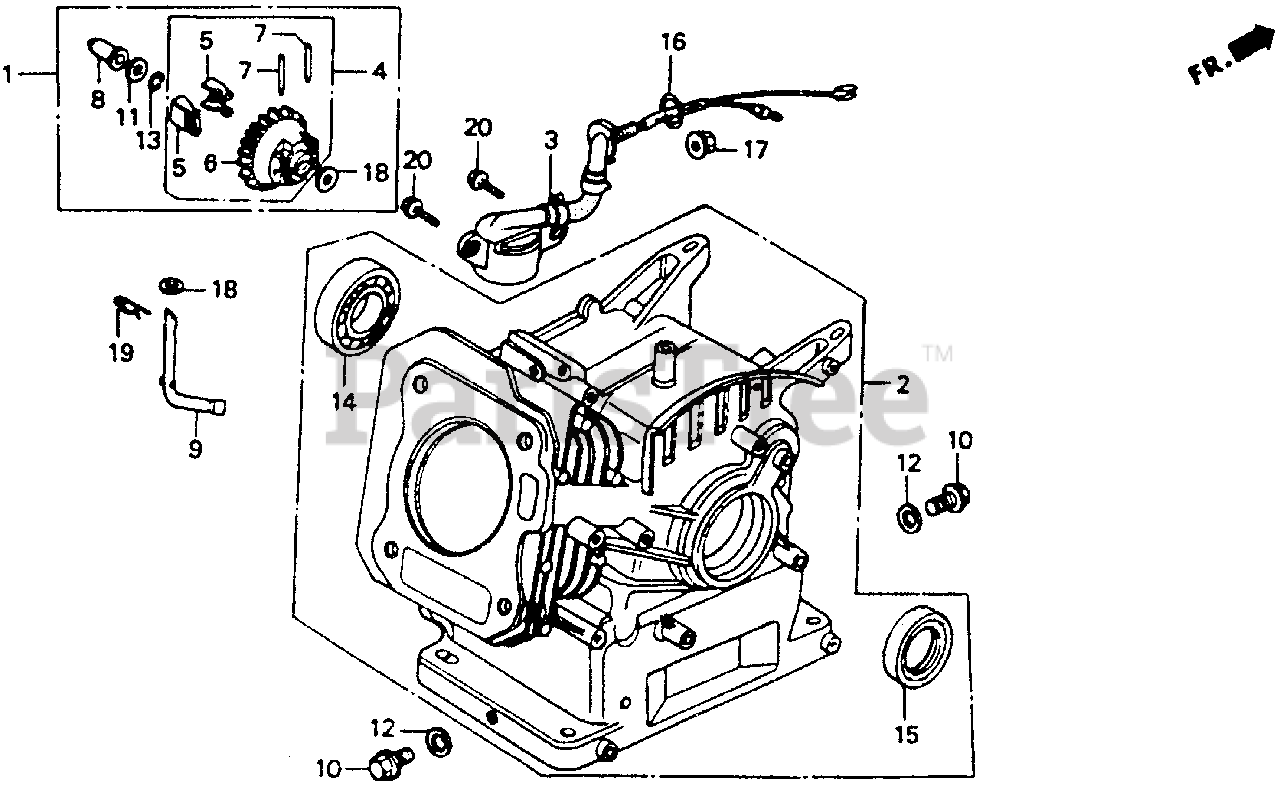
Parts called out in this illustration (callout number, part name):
1	GOVERNOR KIT
2	CYLINDER ASSY.
4	GOVERNOR ASSY.
5	WEIGHT, GOVERNOR
6	HOLDER, GOVERNOR WEIGHT
7	PIN, GOVERNOR WEIGHT
8	SLIDER, GOVERNOR
9	SHAFT, GOVERNOR ARM
10	BOLT, DRAIN PLUG
11	WASHER, THRUST (6MM)
12	WASHER, DRAIN PLUG (10.2MM)
13	CLIP, GOVERNOR HOLDER
14	BEARING, RADIAL BALL (6205TMB) (NTN)
14	BEARING, RADIAL BALL (6205)
15	OIL SEAL (25X41X6)
18	WASHER, PLAIN (6MM)
19	PIN, LOCK (8MM)
